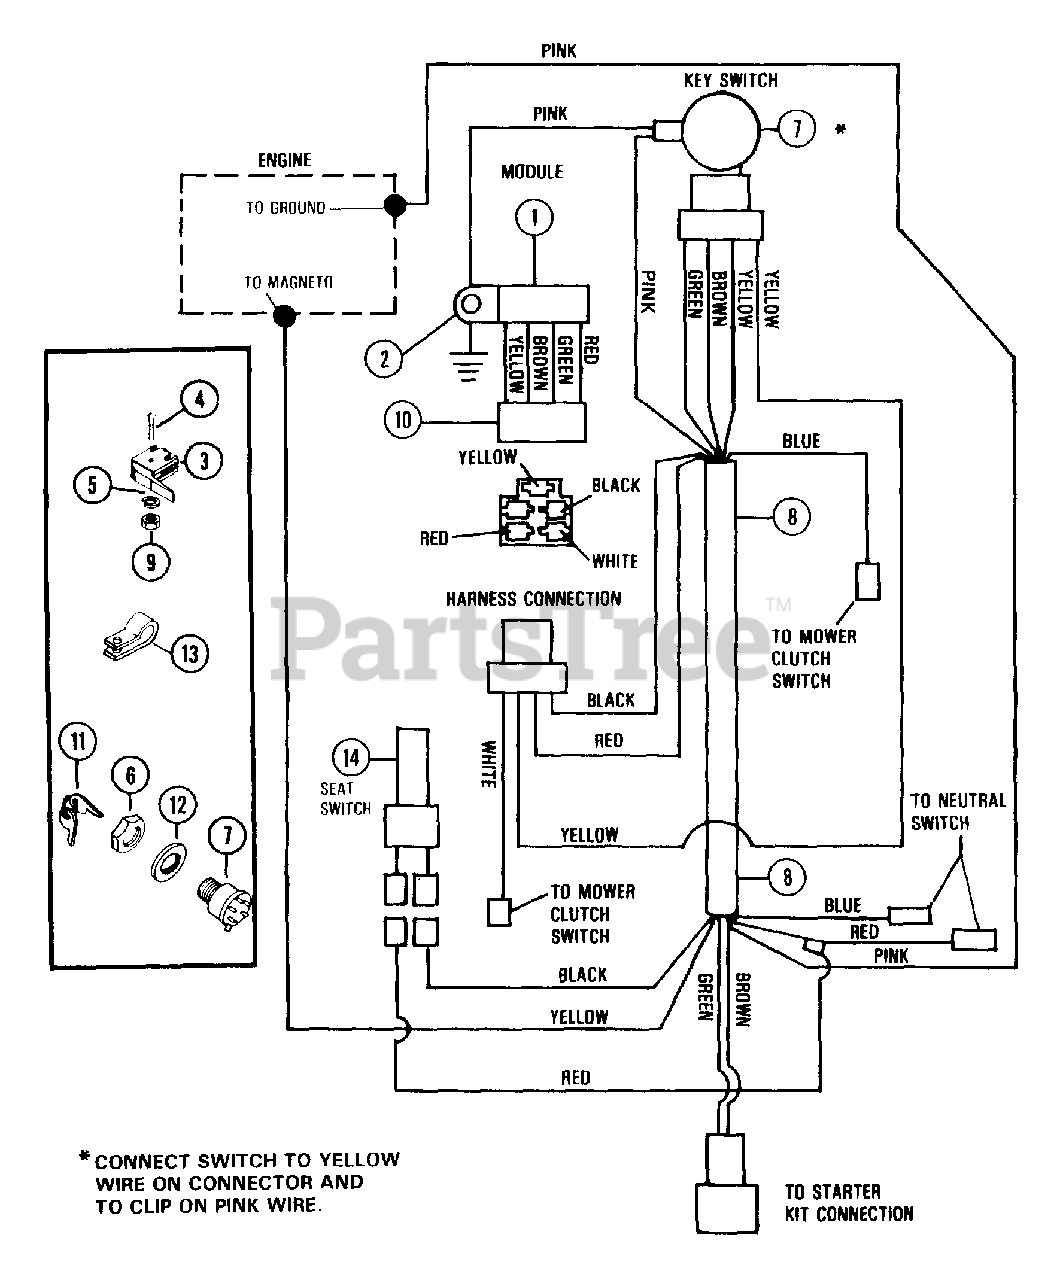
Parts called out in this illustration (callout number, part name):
1	MODULE
2	SCR-TAP 10-12X.50 CRPH PL A
3	SWITCH INTERLOCK
4	SCR-MCH 10-24X1.00 SLRH PL
5	WSHR-LK 10X.047 MED PL
6	NUT .625-32 ALUM
7	SWITCH & KEY SET ASSEMBLY
8	WIRE HARNESS
9	NUT-HEX 10-24 PL
10	CONNECTOR
11	KEYS
12	WSHR-LK-INT .625X.045 PL
14	SWITCH SEAT
